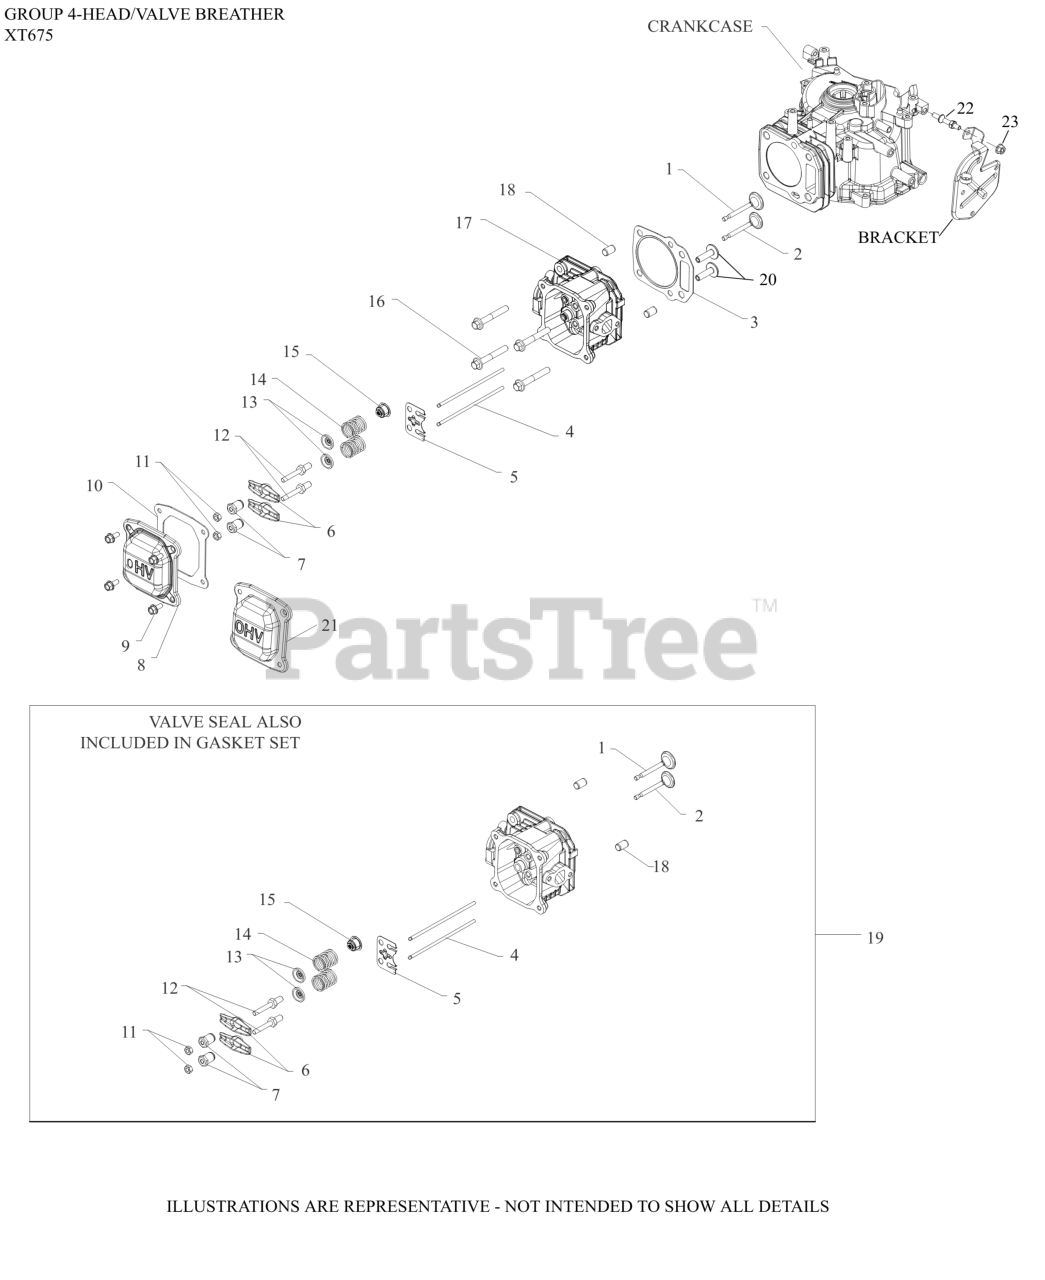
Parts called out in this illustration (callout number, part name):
1	VALVE INTAKE
2	VALVE, EXHAUST
3	KIT HEAD GASKET
4	ROD, PUSH
5	PLATE, PUSHROD GUIDE
6	ARM, ROCKER
7	PIVOT, ROCKER ARM
11	NUT, HEX JAM
12	STUD, ROCKER ARM-USE 14 072 22-S
13	RETAINER, VALVE SPRING
14	SPRING, VALVE
15	SEAL, VALVE STEM
16	SCREW, HEX FLANGE M8
17	HEAD, CYLINDER
18	DOWEL, CYLINDER HEAD-(#1438013S)
19	KIT, VALVE TRAIN
20	LIFTER, VALVE
21	COVER, VALVE
